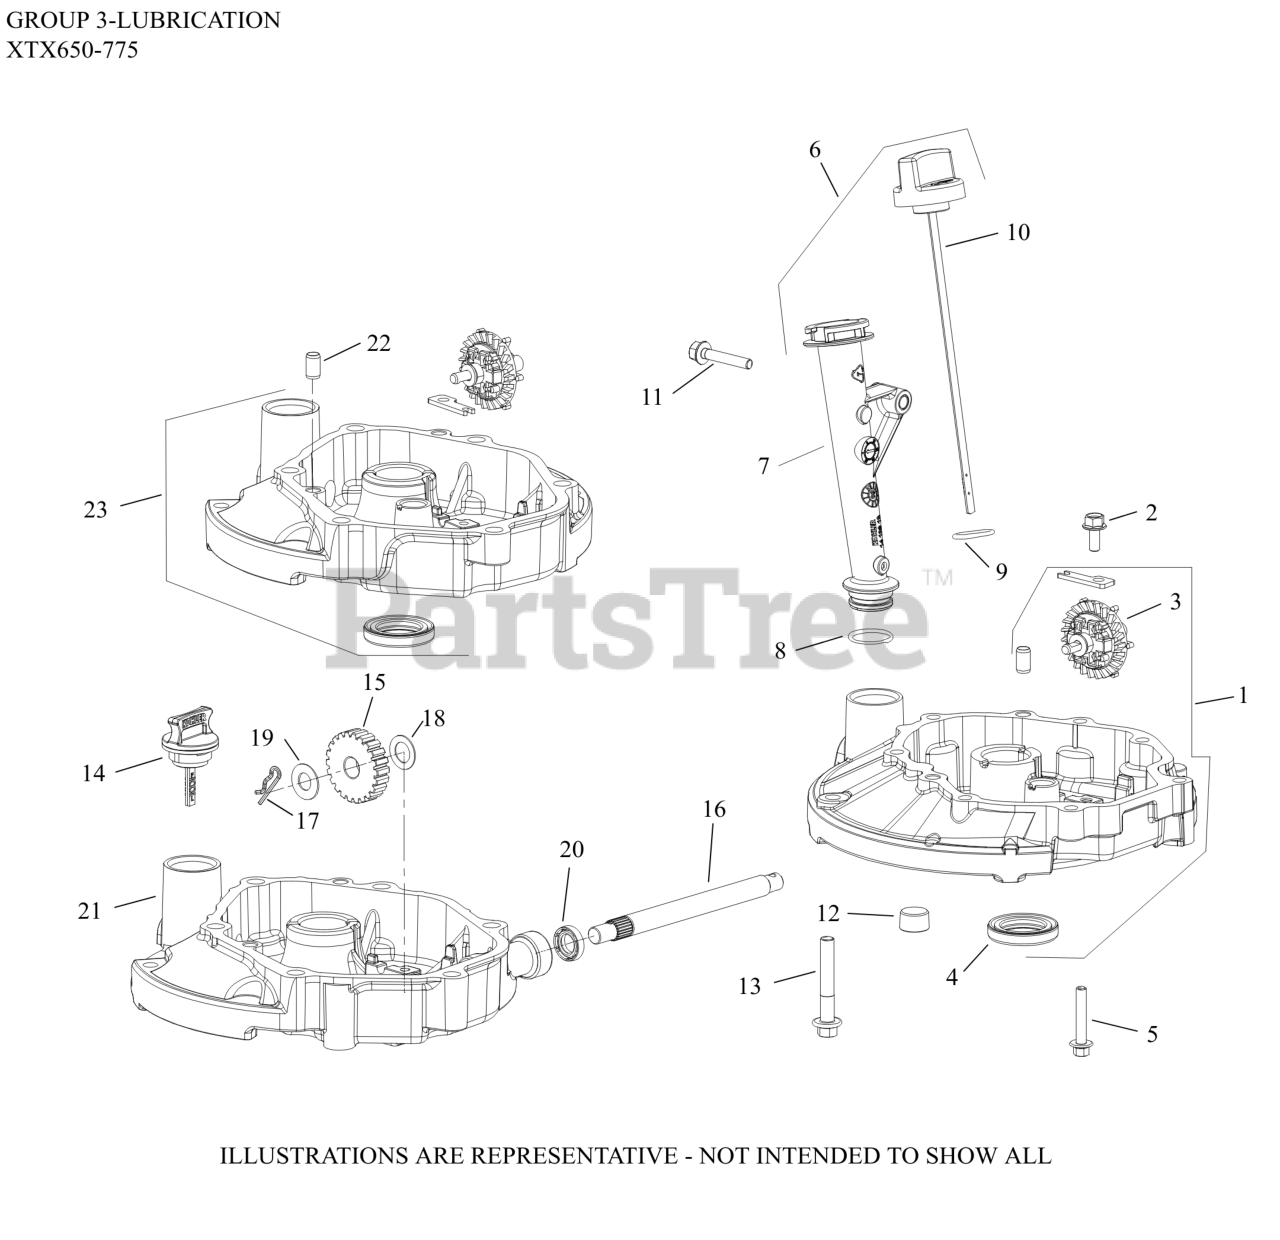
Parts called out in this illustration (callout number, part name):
3	GEAR ASSEMBLY, GOVERNOR
6	KIT, DIPSTICK AND TUBE-(#1412320S)
7	TUBE ASSEMBLY, OIL FILL
8	O-RING, OIL FILL TUBE
9	O-RING (CAP)
10	CAP, DIPSTICK ASSEMBLY
11	SCREW, HEX FLANGE (M6)-(#25086435S)
12	PLUG, PIPE (W/SEALANT)
13	SCREW, HEX FLANGE (M8)-USE 25 086 456-S
22	PIN, DOWEL (8mm)
